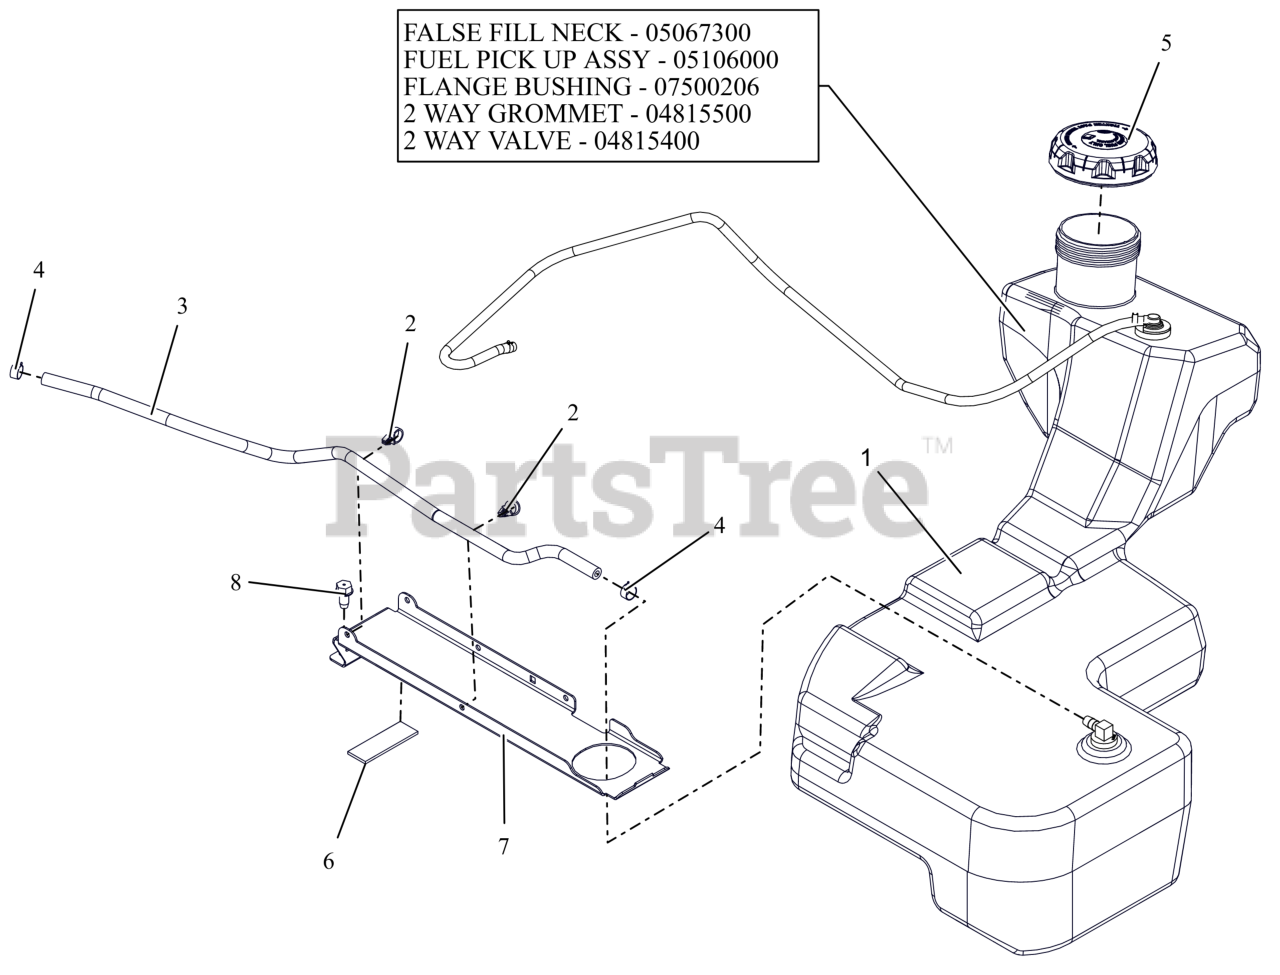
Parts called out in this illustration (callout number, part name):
1	ASM, FUEL TANK-HD
1	INSERT, FUEL NECK FALSE FILL
1	ASM, HD FUEL PICK-UP
1	GROMMET, 2-WAY
1	VALVE, 2-WAY
2	ROUTING CLIP (1/2" ID)
3	HOSE, .25 LOW-PERM BULK GAS
4	CLAMP, FUEL LINE
5	CAP, FUEL VENTIN AUTOLOCK
6	PAD,RBR 1.0"X3.0" W/ADHESIVE
7	BRKT, FUEL TANK HOLD DOWN
8	SCR,TAP .375-16X.75 HWH TR ZCC
